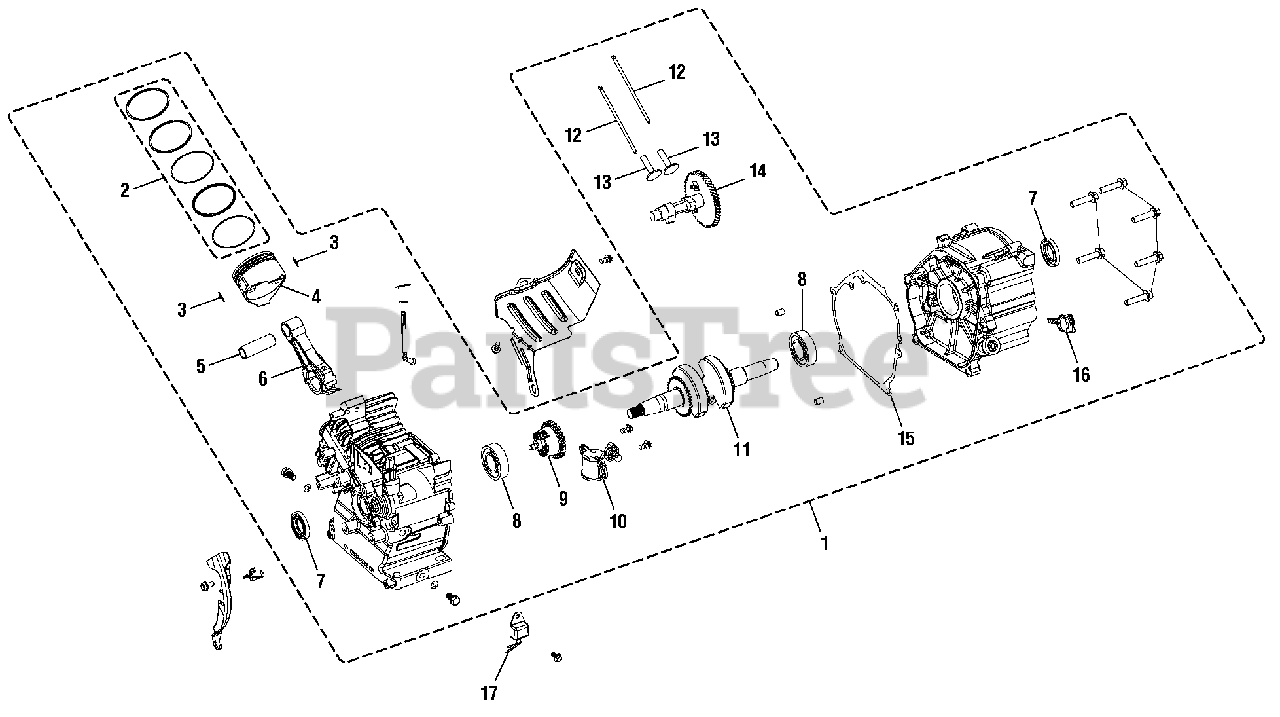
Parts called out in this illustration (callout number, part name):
1	Engine Small Block
2	Piston Ring Set
3	Piston Clip
4	Piston
5	Piston Pin
6	Connecting Rod Assembly
7	Oil Seal
8	Ball Bearing
9	Governor Assembly
10	Switch Assembly (Oil Level)
11	Crankshaft Assembly
12	Valve Lifter Assembly
13	Valve Tappet
14	Camshaft Assembly
15	Casecover Gasket
16	Dipstick
17	Amplifier
